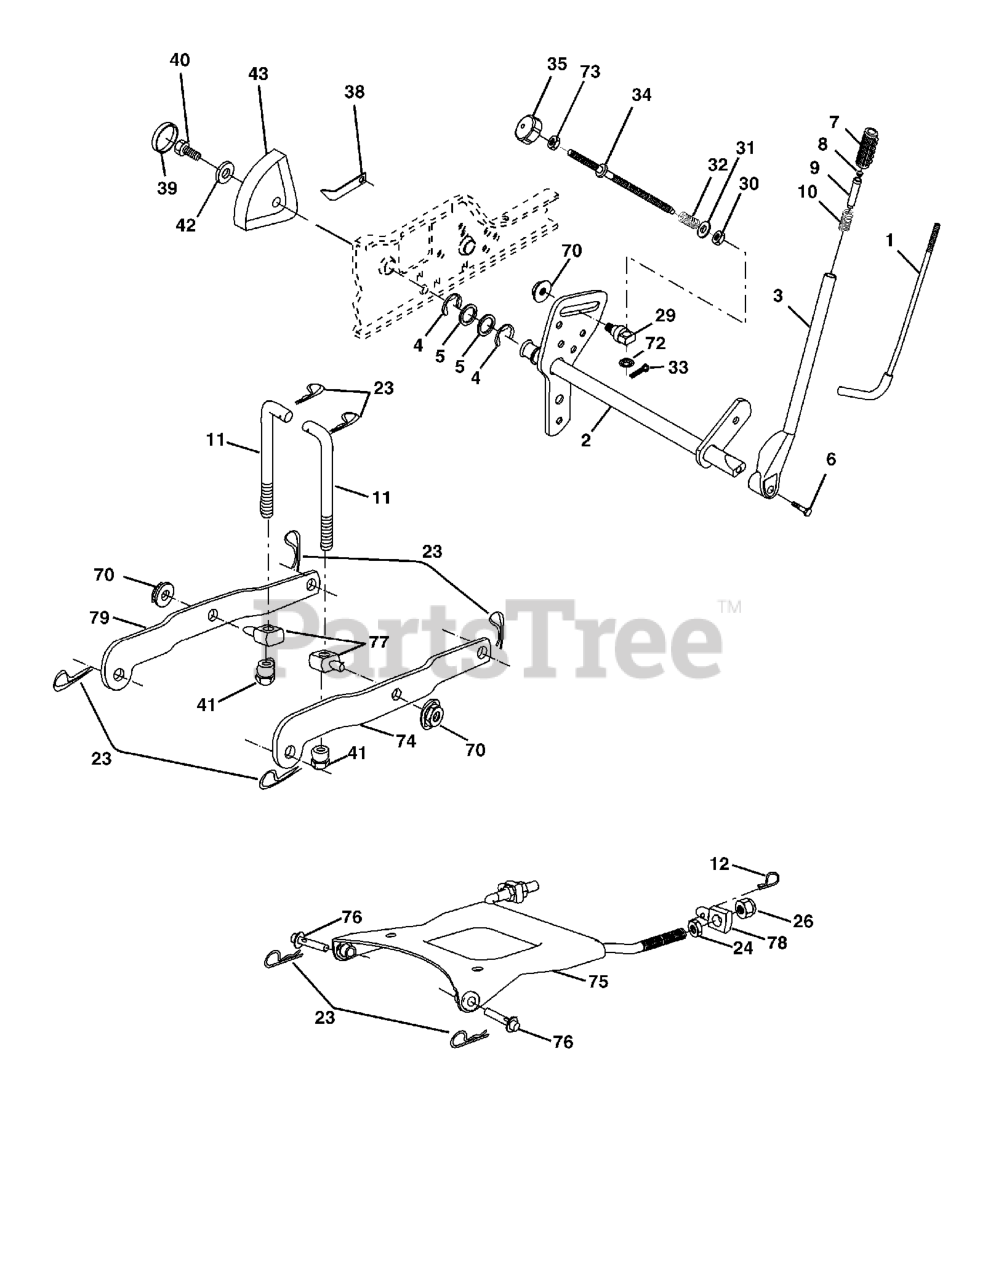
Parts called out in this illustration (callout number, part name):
1	LEVER ROD LT
2	SHAFT ASM., LIFT VGT
3	LEVER ASSY-LIFT RH
4	E-RING
5	Washer 29/32 x 1 - 1/4 x 16 Ga.
6	Bolt, Fin Hex 3/8-16 x 1-1/12
7	GRIP HANDLE
8	PLUNGER BUT KIT
9	PLUNGER BUT KIT
10	SPRING 0.620D X 2.125
11	LIFT LINK
12	SPRING RETAINER
23	RETAINER-SPRNG RB
24	NUT.HEX.JAM.1/2-13
26	NUT.LK.W/WSH.1/2.
29	TRUNNION
30	NUT T
31	WASHER
32	SPRING.COMP.INF.H
33	COTTER PIN
34	ROD.LIFT.ADJUSTABLE
35	KNOB INF 3/8-16
38	POINTER, HEIGHT INDICATOR(2 2)
39	PLUG,HOLE
40	SCREW 5/16-18X1
41	NUT, LIFT LINK 7/16-20
42	WASHER
43	HEIGHT INDICATOR
70	NUT
72	NUT PUSH M
73	NUT
74	ARM SUSP REAR RH
75	PLATE ASM SUSP FRONT
76	PIN.FLANGE
77	TRUNNION
78	TRUNNION
79	ARM SUSP. REAR LH
